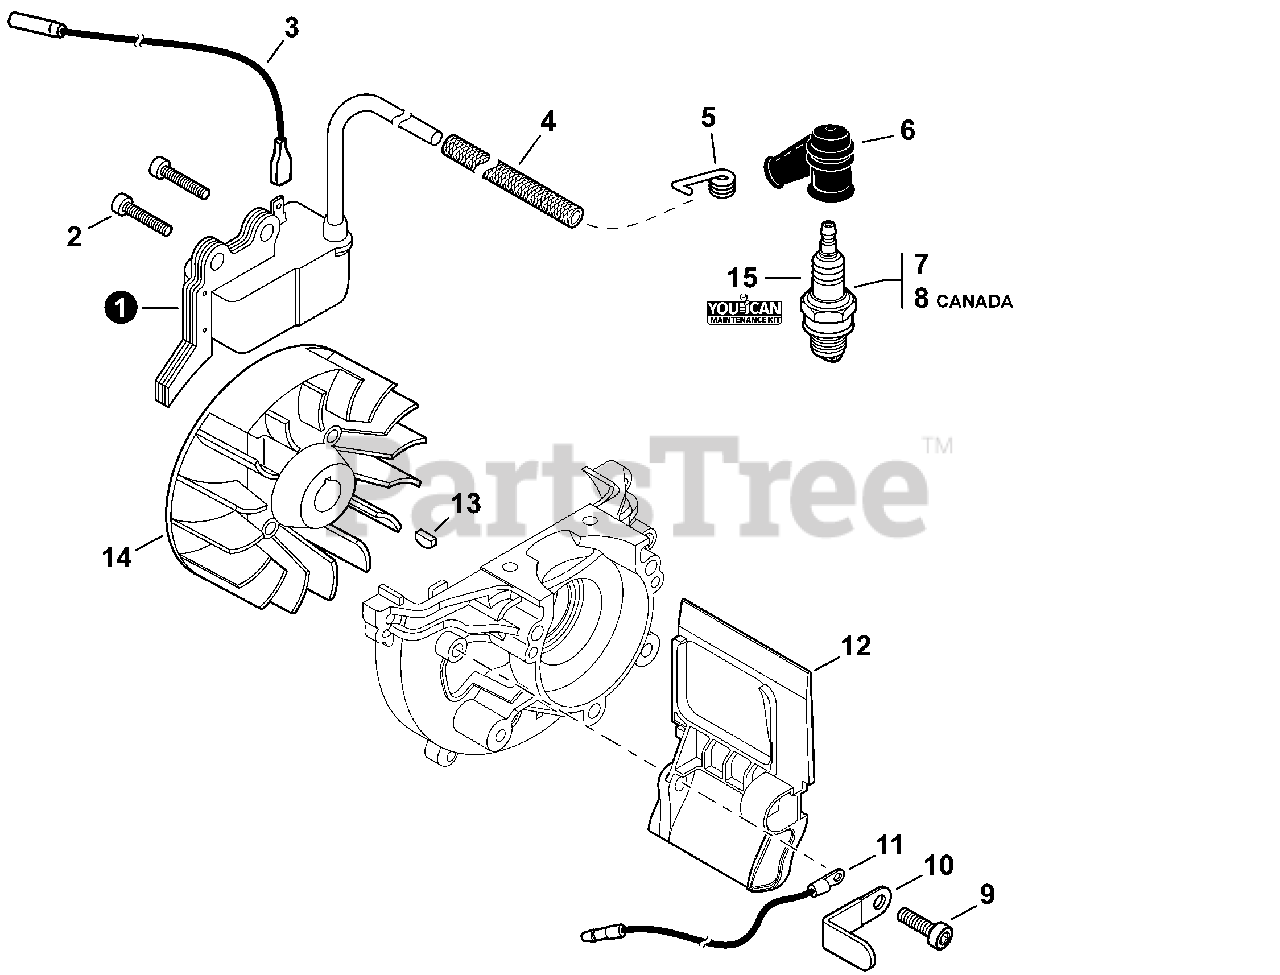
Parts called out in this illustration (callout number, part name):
1	COIL, IGNITION
2	BOLT, TORX 4×20
3	LEAD - IGNITION L= 210
4	TUBE, INSULATOR
5	TERMINAL, SPARK PLUG
6	CAP, SPARK PLUG
7	SPARK PLUG - BPM8Y
8	SPARK PLUG - BPMR8Y
9	BOLT, TORX 5×12
11	LEAD - GROUND L= 115
12	PLATE, INSULATOR
13	KEY, WOODRUFF
14	FLYWHEEL
15	TUNE-UP KIT - YOUCAN™
